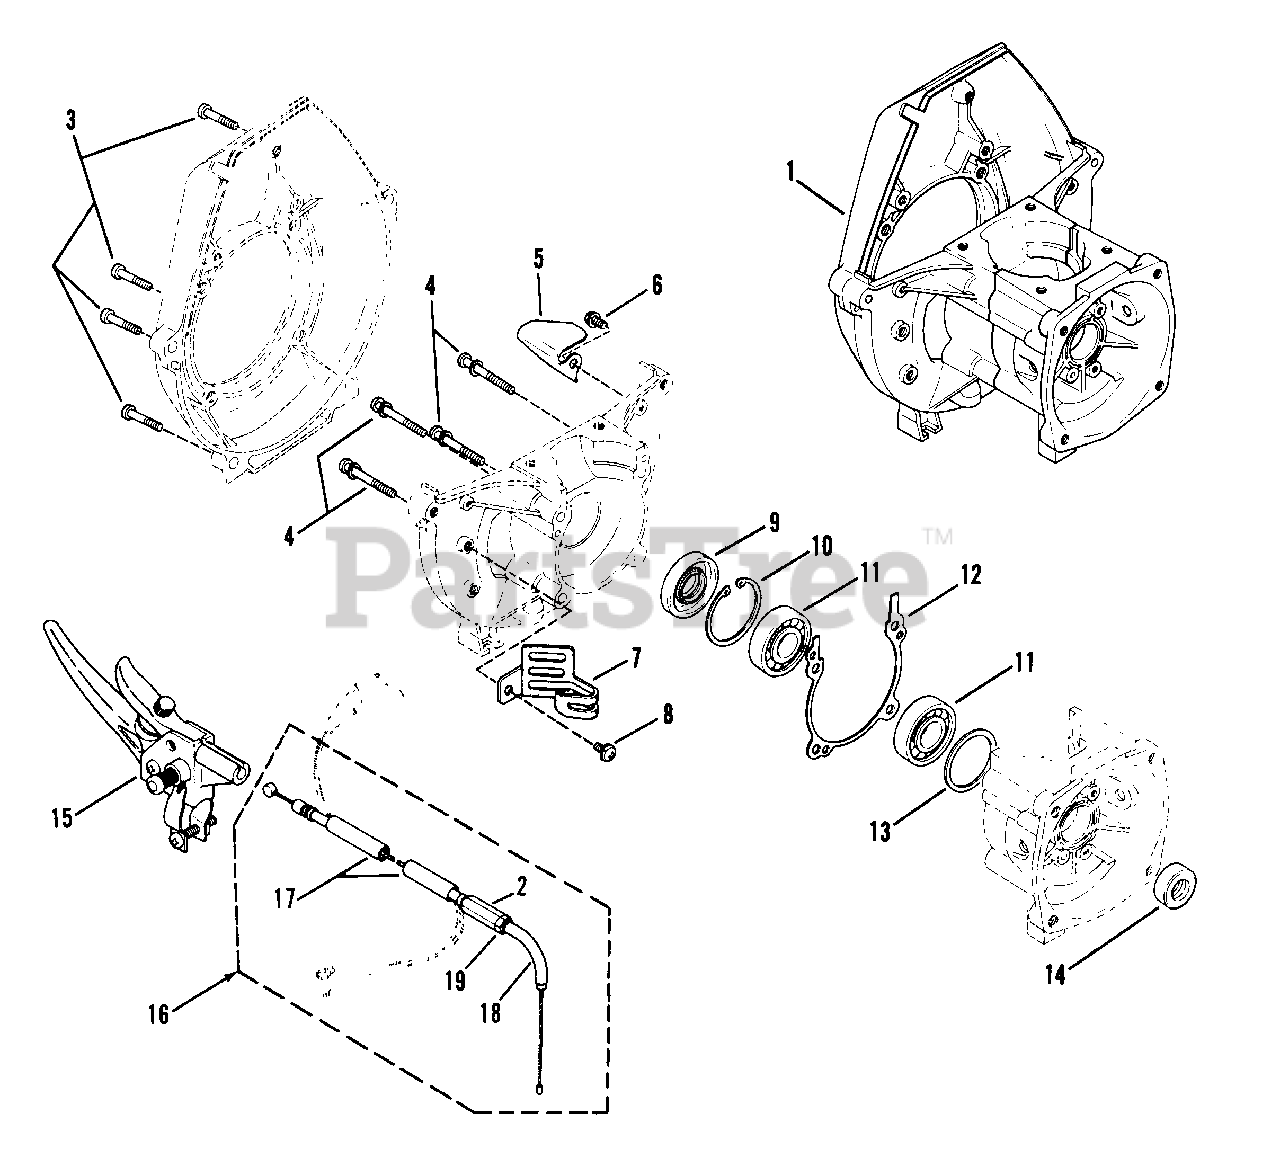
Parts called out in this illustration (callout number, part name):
1	CRANK CASE ASSM'Y.
2	NUT, Adjusting
9	SEAL, Oil
10	SNAP-RING
11	BEARING
12	GASKET, Crankcase
13	SHIM (Set of 3)
14	SEAL, Oil
15	LEVER, Throttle
16	CABLE, Throttle Assm'y.
17	CABLE & JACKET
19	NUT, Lock
